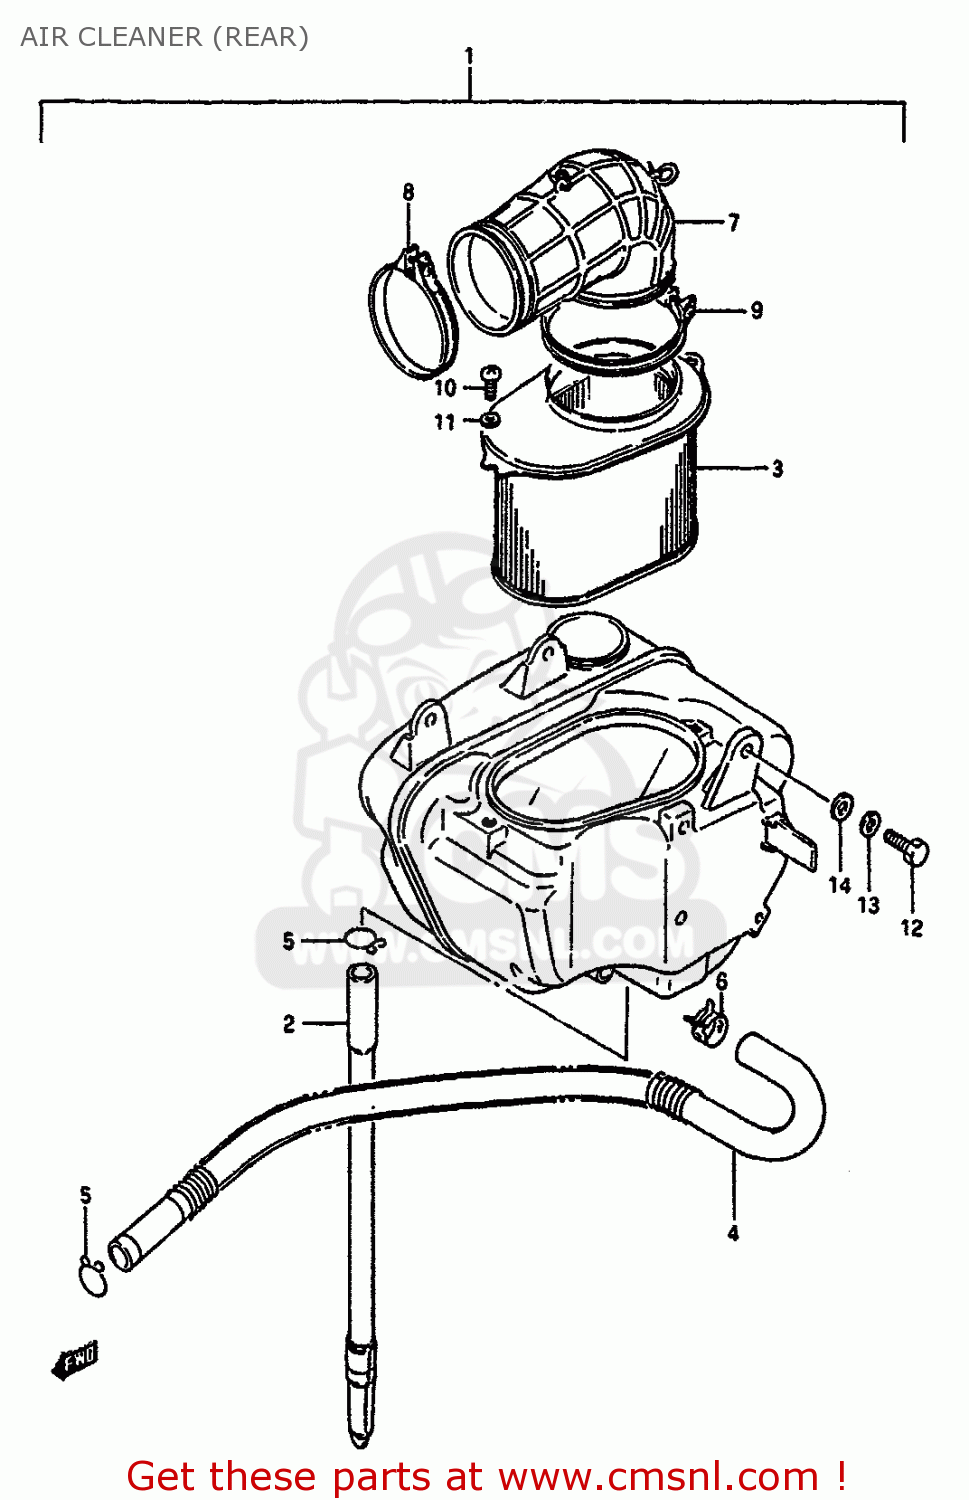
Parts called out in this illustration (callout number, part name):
1	CLEANER,AIR,RR
2	DRAIN TUBE
3	FILTER,AIR CLEANER
4	TUBE SET,BREATHER
5	CLIP
6	CLIP
7	TUBE,AIR CLEANER OUTLET
8	CLAMP
9	CLAMP
10	SCREW
11	WASHER,LOCK
12	BOLT
13	WASHER,LOCK
14	WASHER(6.5X16X1.2)
